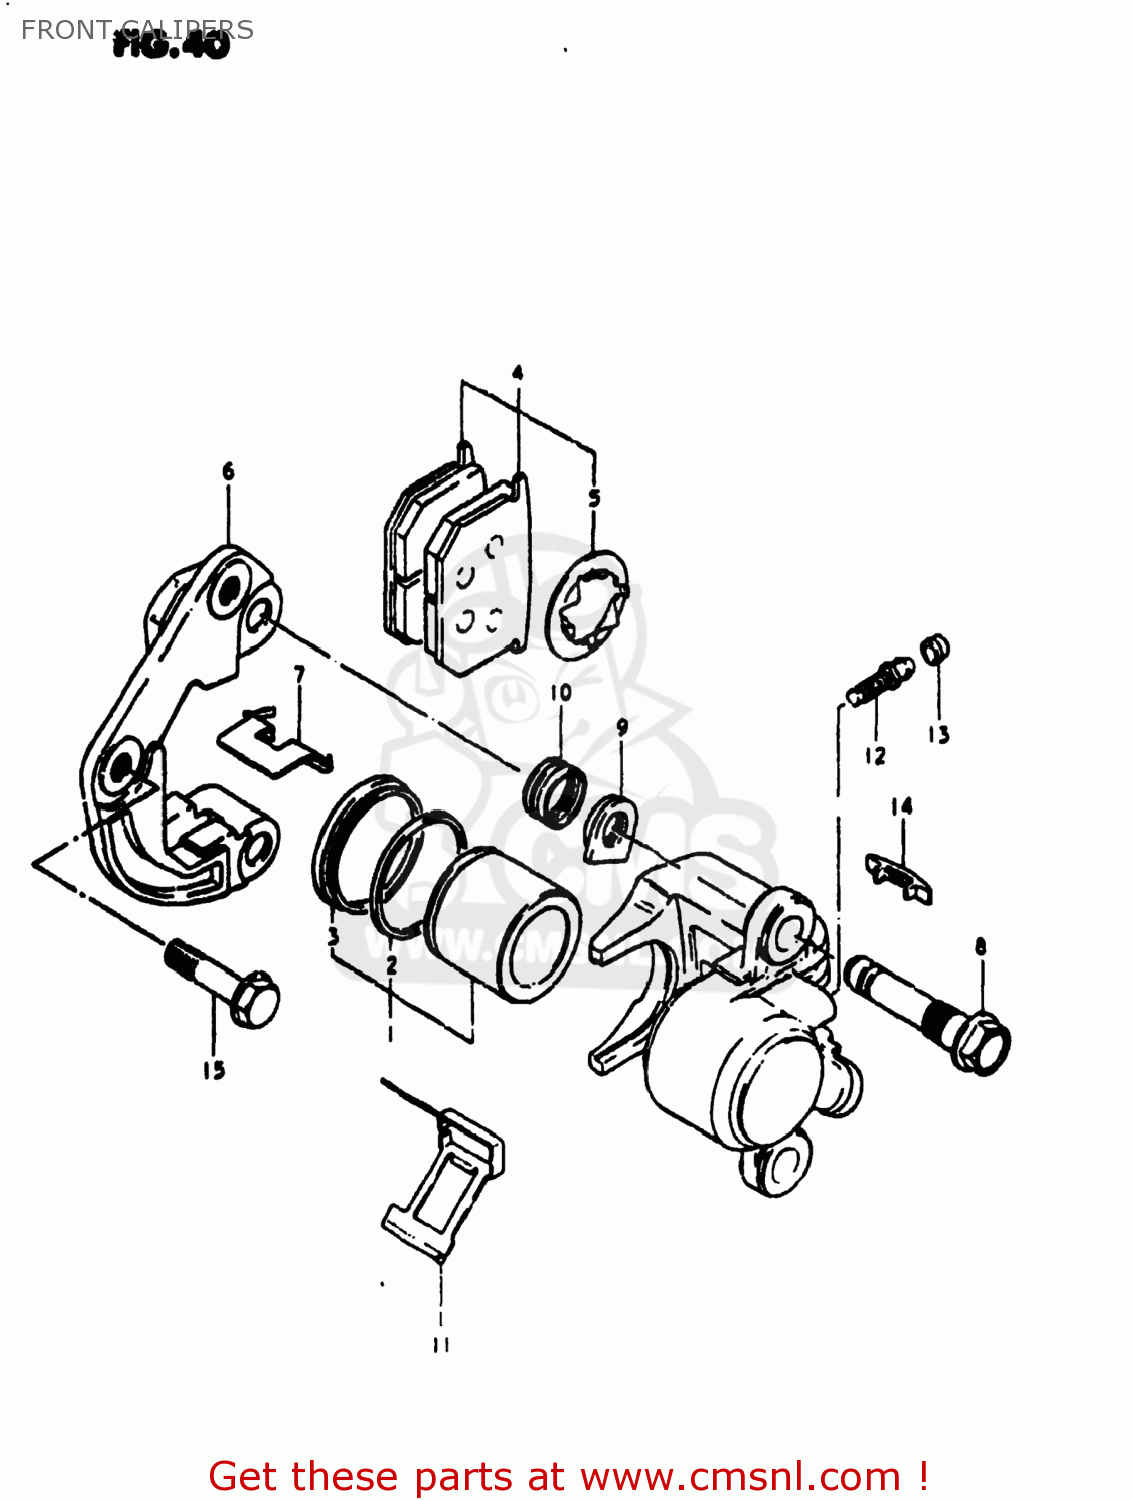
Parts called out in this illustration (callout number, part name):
0	CALIPER ASSEMBLY,LEFT
1	PISTON SET
2	SEAL,PISTON
3	BOOT,PISTON
4	PAD & SHIM SET (MCA)
5	SHIM,PAD
6	HOLDER,CALIPER,LEFT
7	GUIDE,PAD
8	AXLE,CALIPER
9	NUT,CALIPER AXLE
10	BOOT
11	SPRING
12	BREATHER
13	CAP,BLEEDER PL
14	COVER,INDICATOR
15	BOLT(10X37)
